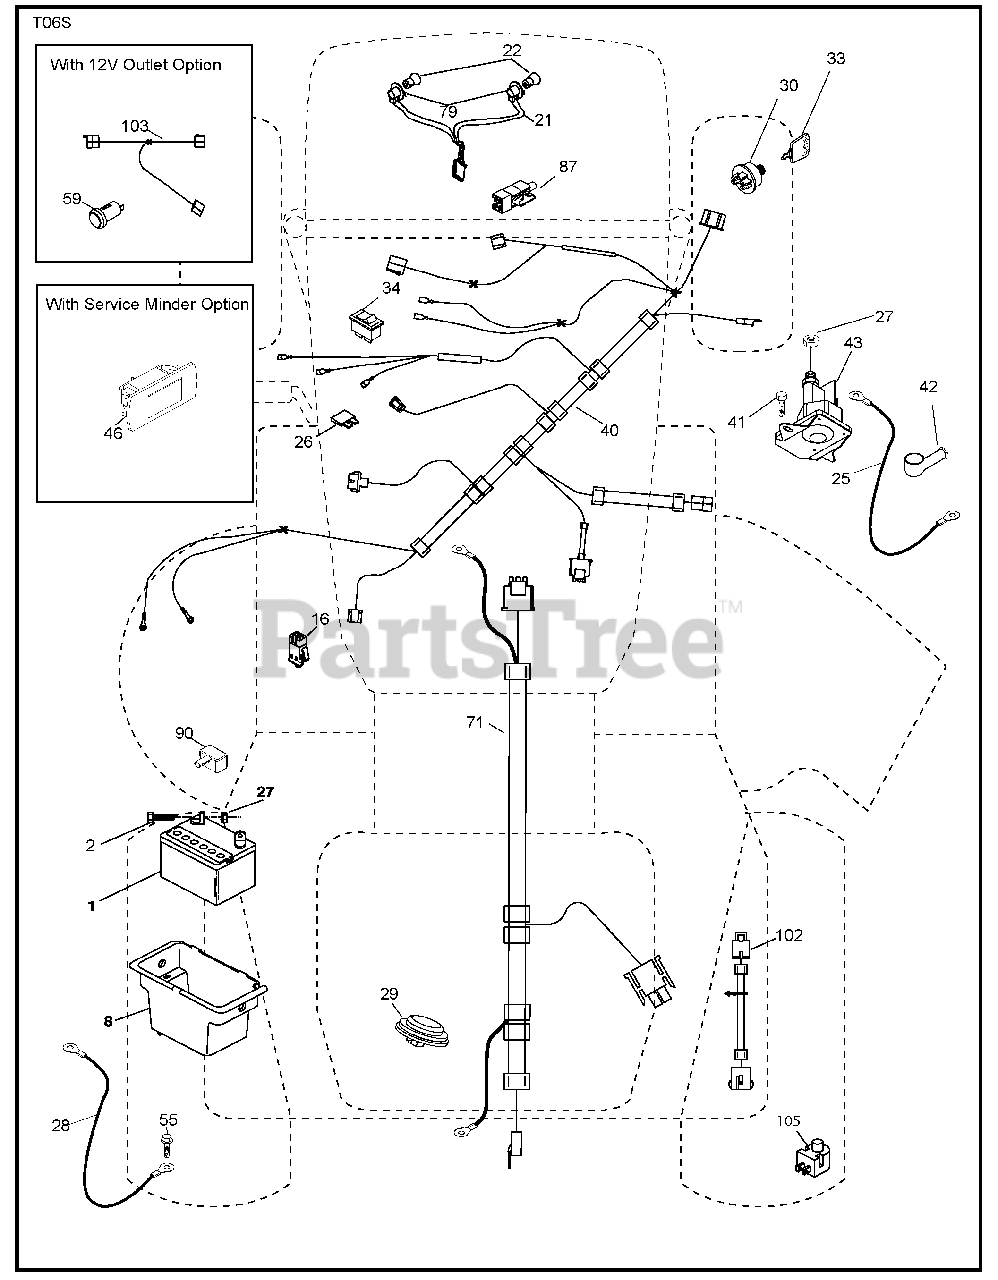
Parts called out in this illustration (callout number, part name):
1	Battery
2	Bolt Hex Head 1/4-20 x 3/4
8	Box Battery
16	Switch Interlock Push-In
21	Harness Socket Light w/4152J
22	Bulb Light
25	Cable Starter
27	Nut Keps Hex 1/4-20 unc
28	Cable, Ground
29	Switch, Seat
30	Switch, Ign
33	Key / Chain
34	Switch Light / Reset
40	Harness Ign.
41	Screw Thd Cut 1/4-20 x 1/2
42	Cover, Terminal
43	Solenoid
46	Gauge Hourmeter
55	Screw Thdrol 5/16-18 x 3/4 TYTT
71	Harness Ign. Dash
79	Socket Asm. Bulb Twistlock
87	Switch Interlock Clutch Cable
90	Cover Terminal
102	Harness Pigtail
105	Switch Reverse TT GT
